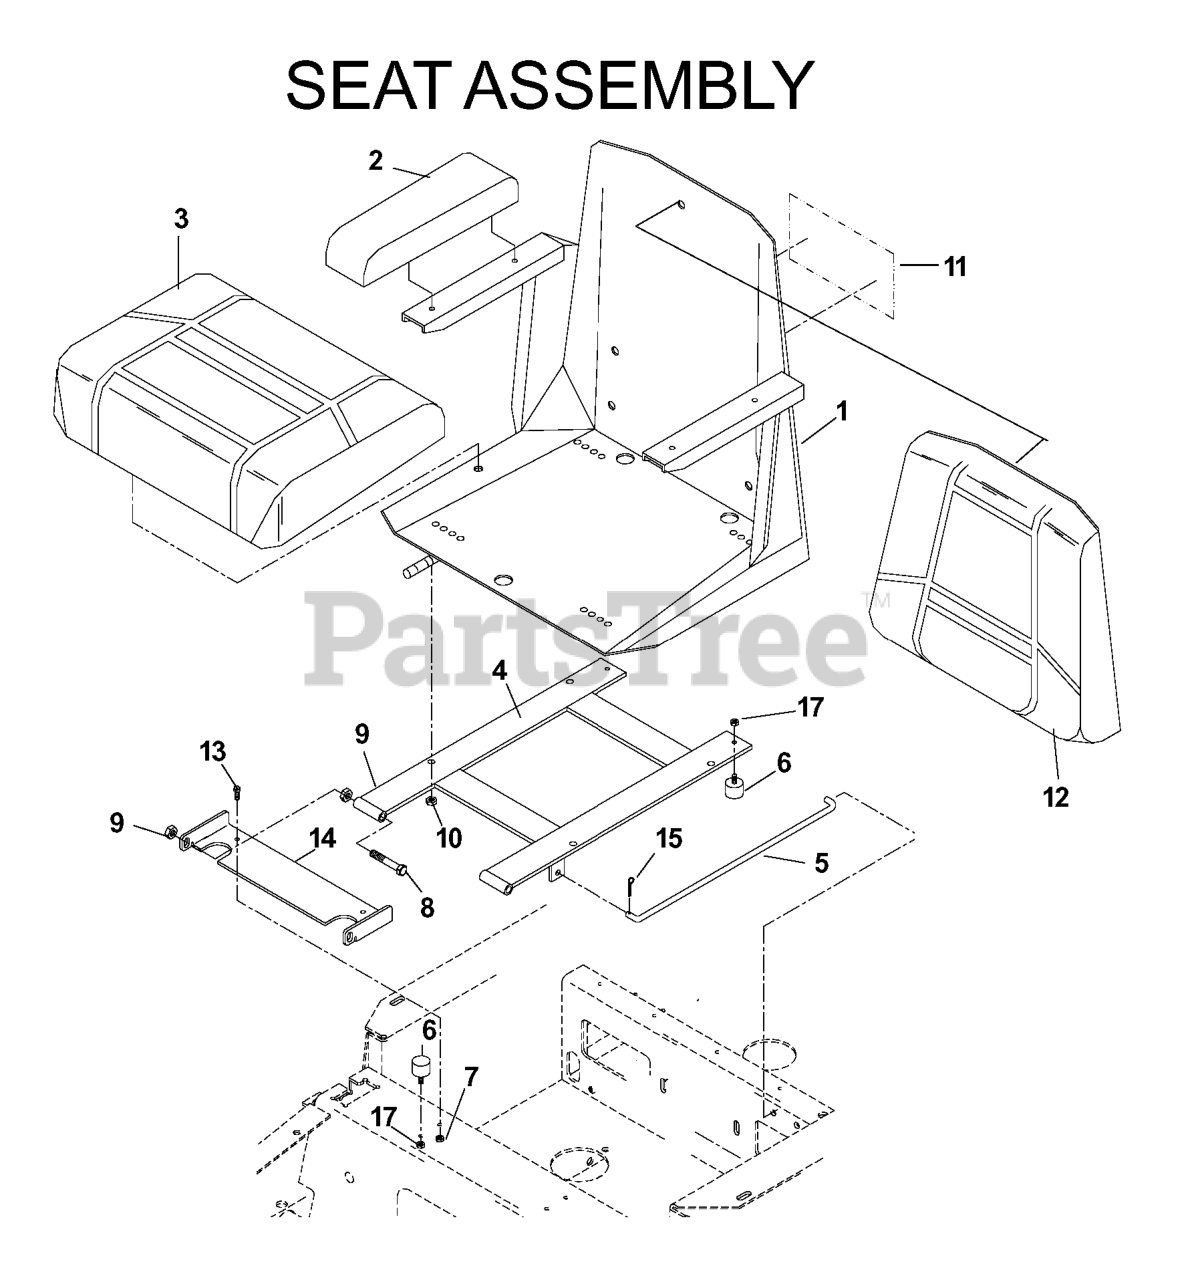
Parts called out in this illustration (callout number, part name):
1	SEAT, COMPLETE
2	ARM REST CUSHIONS/PAIR
3	SEAT CUSHION W/SWITCH
4	SEAT MOUNT
6	STUD/PLATE MOUNT
7	NUT 1/4C CENTERLOCK
8	HCS 3/8C X 3
9	NUT 3/8C CENTERBLOCK
10	NUT 5/16C CENTERLOCK
11	DECAL, CROWN H
12	SEAT, BACK CUSHION
13	HCS 1/4C X 3/4 HCS
14	SEAT BRKT W/DECAL
15	RP_COTTER PIN 1/8 X 3/4
16	SEAT RAILS
17	NUT.1/4-20.HEX.NYLOC.ZD
